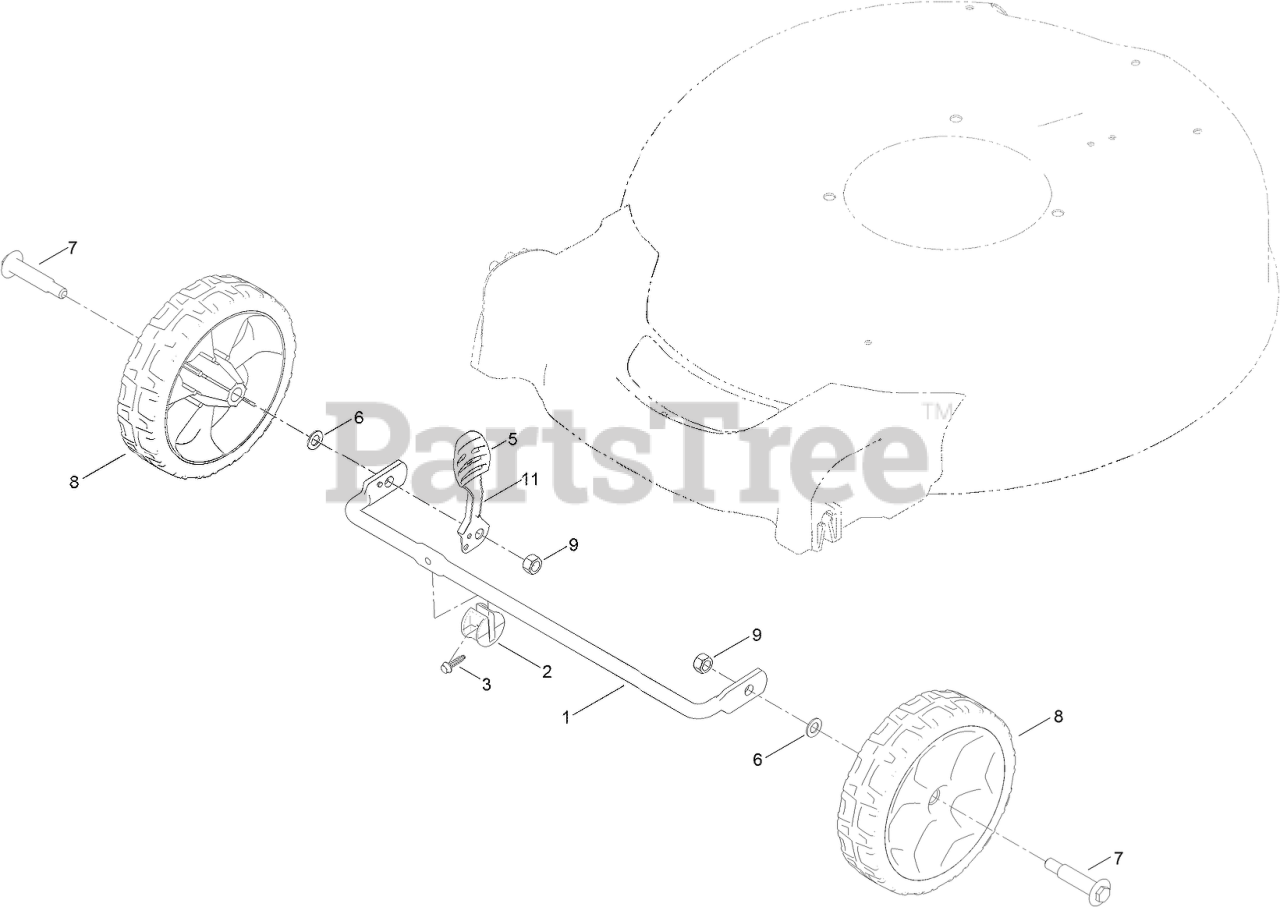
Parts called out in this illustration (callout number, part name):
1	AXLE-FRONT
2	STOP-AXLE
3	SCREW-HWH
5	KNOB-LEVER, HOC
6	WASHER
7	BOLT-SHOULDER
8	7 INCH WHEEL ASM
9	NUT-HEX
11	ARM-SPRING
